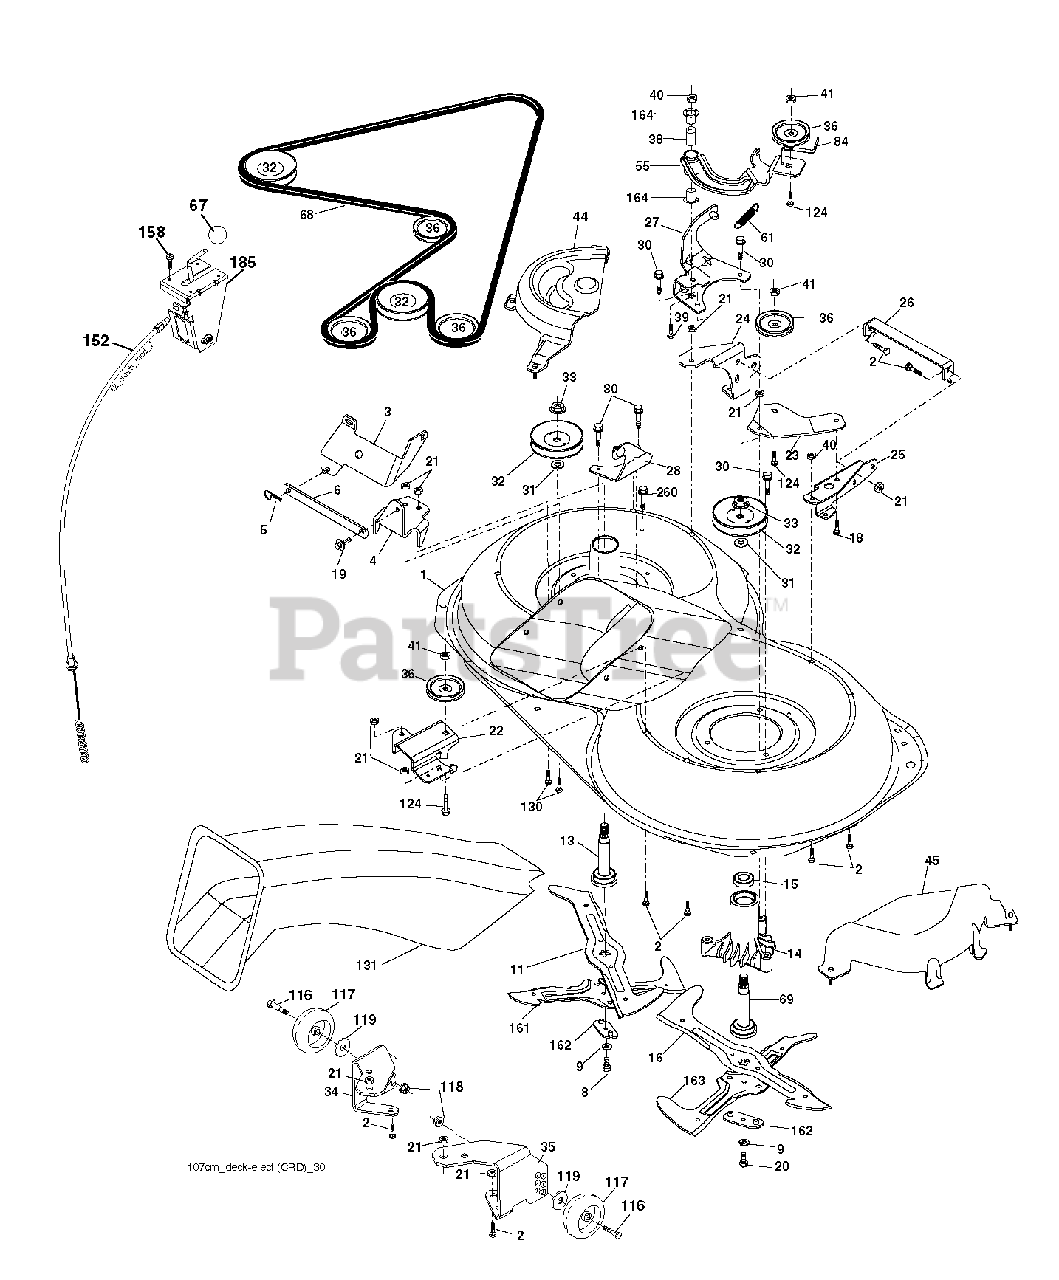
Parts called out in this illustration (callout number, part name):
2	BOLT
3	BRACKET.ASM.BAR.SWAY.CHASS
5	RETAINER-SPRNG RB
6	BAR SWAY
8	Bolt, 3/8-24 X 1.25 Gr8
9	LOCKWASHER
11	BLADE.3N1.LH.CRD
13	SHAFT ASM VENT
16	BLADE.3N1.RH.CRD
19	BOLT SHD 5/16-18
20	BOLT.3/8-24X1.25GR8. LHTHRD
21	LOCKNUT
22	BRACKET
23	BRACKET
27	BRACKET
30	SCREW, WASHER HEAD
31	WASHER.SPACER.MANDREL
33	NUT.FLANGE.LOCK.TOP
36	PULLEY.IDLER.4.25
40	LOCKNUT
41	NUT LOCK FLG 3/8-16 UNC
67	KNOB T (3/8 HOLE)
68	HEX-BELT 107 MOWER
69	SHAFT.ASM.W/LWR.BRG.RH.THREAD
84	KEEPER, BELT IDLER
116	BOLT.SHOULDER.3/8-16X3-5/8
117	WHEEL. GUAGE RALLY
118	NUT LOCK FLG 3/8-16 UNC
124	BOLT.3/8-16X1.50
158	SCREW
164	BRNG T
185	HEAD ASM. CABLE CLUTCH
260	SCREW 3/8-16X1/2
